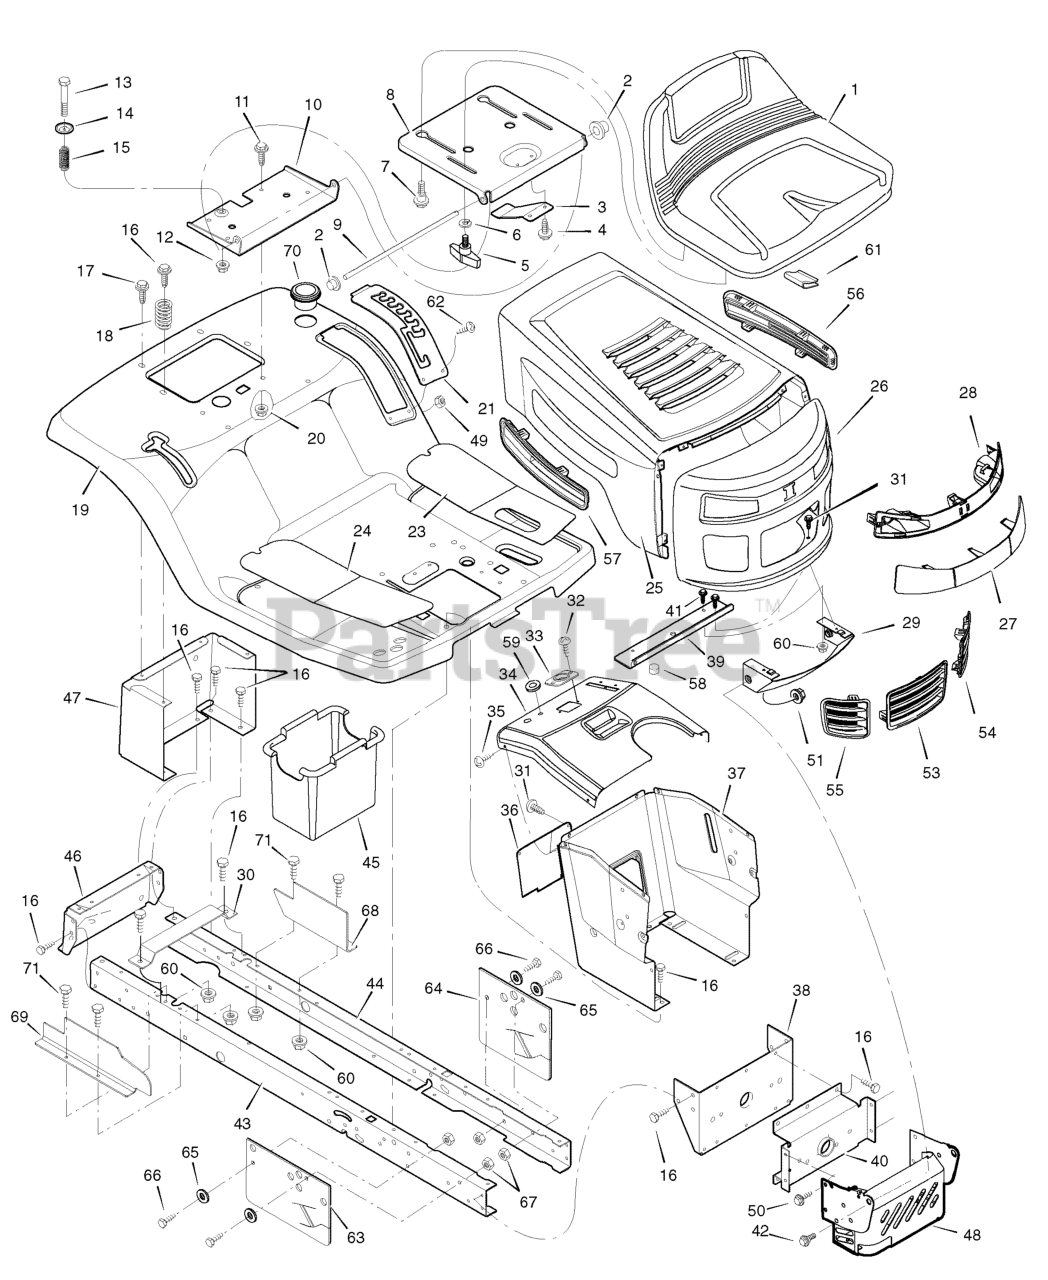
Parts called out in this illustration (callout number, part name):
2	CAP, Push On
5	BOLT, Wing
6	WASHER
7	BOLT, Shoulder
8	SUPPORT, Seat
9	ROD, Pivot
10	BRACKET, Pivot
11	BOLT
13	BOLT, Shoulder
19	DECK, Seat
20	NUT
21	PLATE, Index
23	MAT, Left
24	MAT, Right
25	HOOD, WM1
28	HOUSING, Headlamp
29	BRACKET, Lower Pivot
30	SUPPORT, Battery
33	BEARING, Steering
36	PANEL, Access
37	SUPPORT, Dash
38	BRACKET, Rear Hanger
39	BRACKET, Support
40	AXLE, Hanger
42	BOLT, Shoulder
43	FRAME, Right
44	FRAME, Left
45	CONTAINER, Battery
46	PLATE, Hitch
47	PANEL, Rear
48	SHIELD, Heat
51	NUT
53	INSERT, Center Grille
54	INSERT, Left Grille
55	INSERT, Right Grille
56	INSERT, Left Hood
57	INSERT, Right Hood
59	GROMMET, Parking Brake
60	NUT
61	S-CLIP, Black
63	GUARD, Rubber, RH, Black
64	GUARD, Rubber, LH, Black
66	CAPSCREW, Hex Head, 5/16-18 x 1
67	NUT, Hexlock
68	PLATE, Cover, LH
69	PLATE, Cover, RH
70	HOLDER, Cup
71	BOLT, Hex
